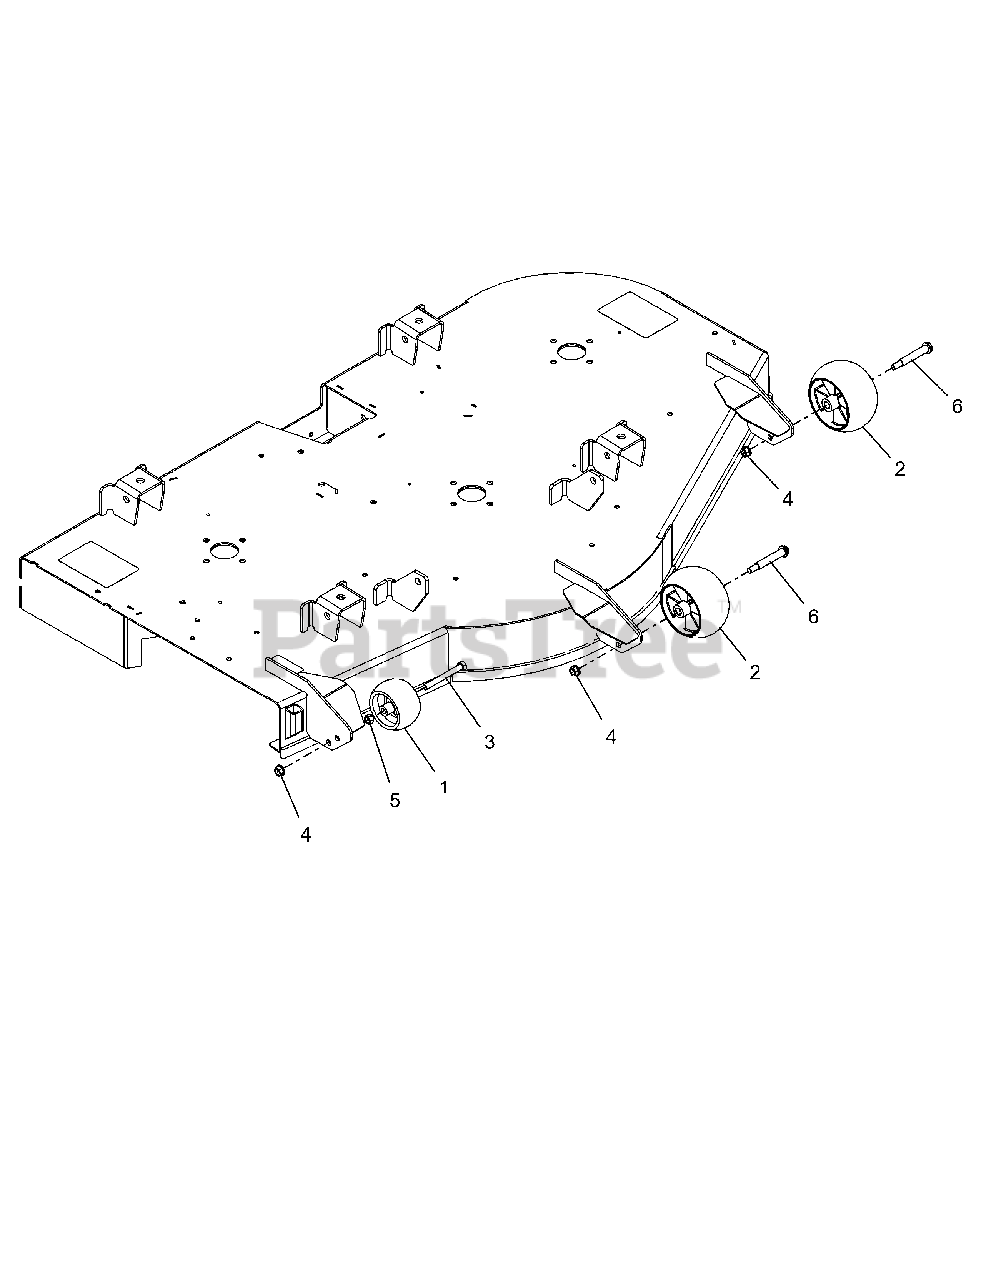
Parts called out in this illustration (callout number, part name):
2	ANTI-SCALP WHEEL - 5X OS
3	BLT, HEX .38-16X3.50 G5 ZCC
4	NUT-LK-TOP-FLG .38-16 ZC120
5	@NUT-HEX .38-16 YWZC
6	BLT-SHLDR .38-16X2.50 HWH G5
